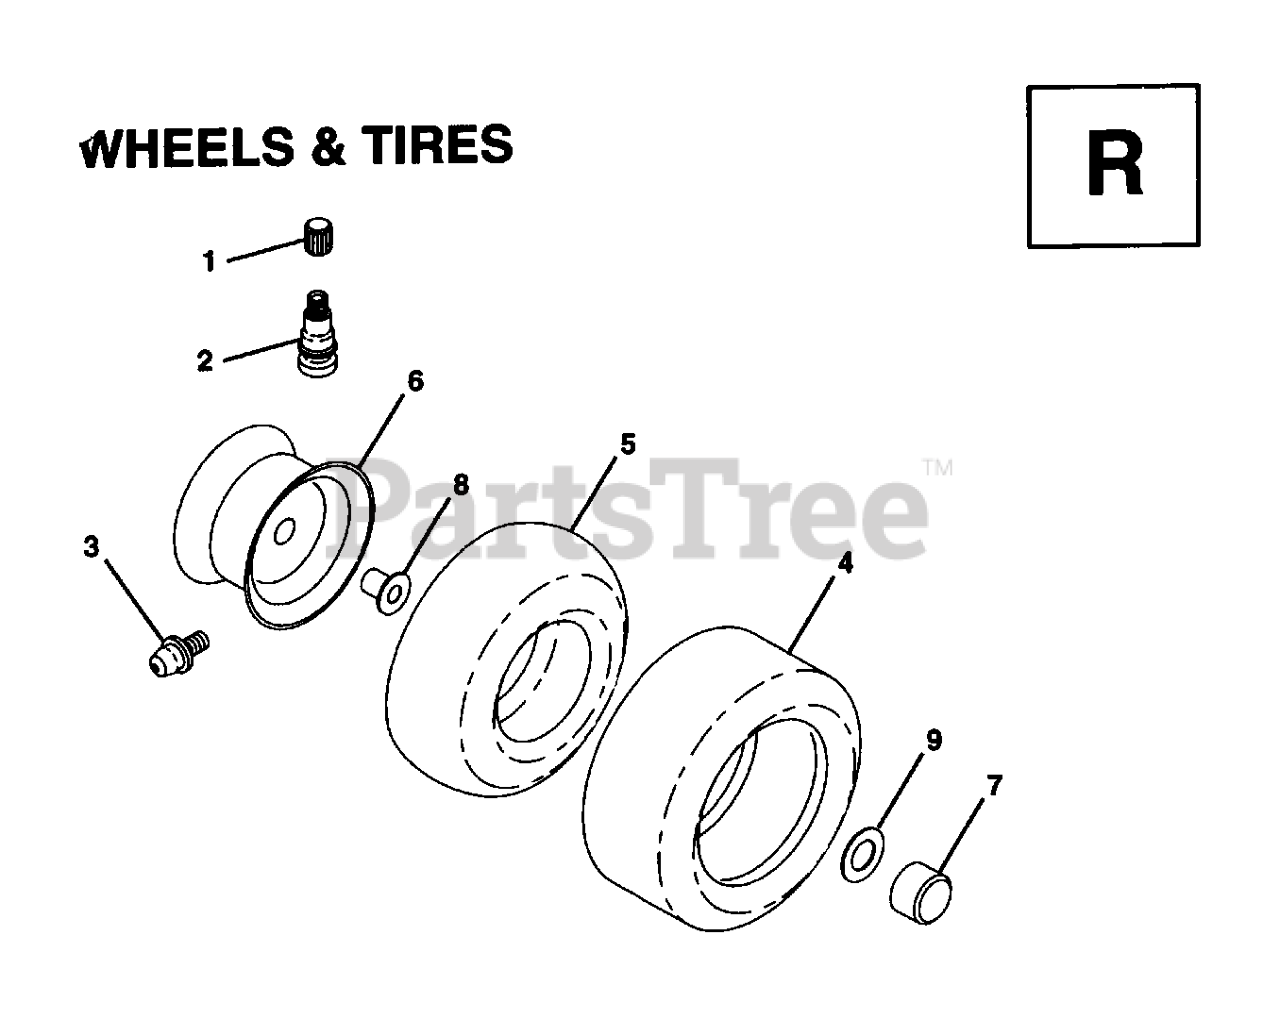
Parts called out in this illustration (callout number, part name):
2	VALVE STEM LT
3	FITTING LT
4	TIRE.13X5-6.TURF.SAVER.FRONT
4	TIRE FRONT 15X6-6
4	TIRE HEAVY DUTY
5	TUBE.5.3/4.5/6
5	TUBE.16X6.5/7.5-8
6	RIM-FRONT
6	RIM ASM REAR 8"
7	CAP.HUB.FRONT.LT.BLACK
8	BEARING T
